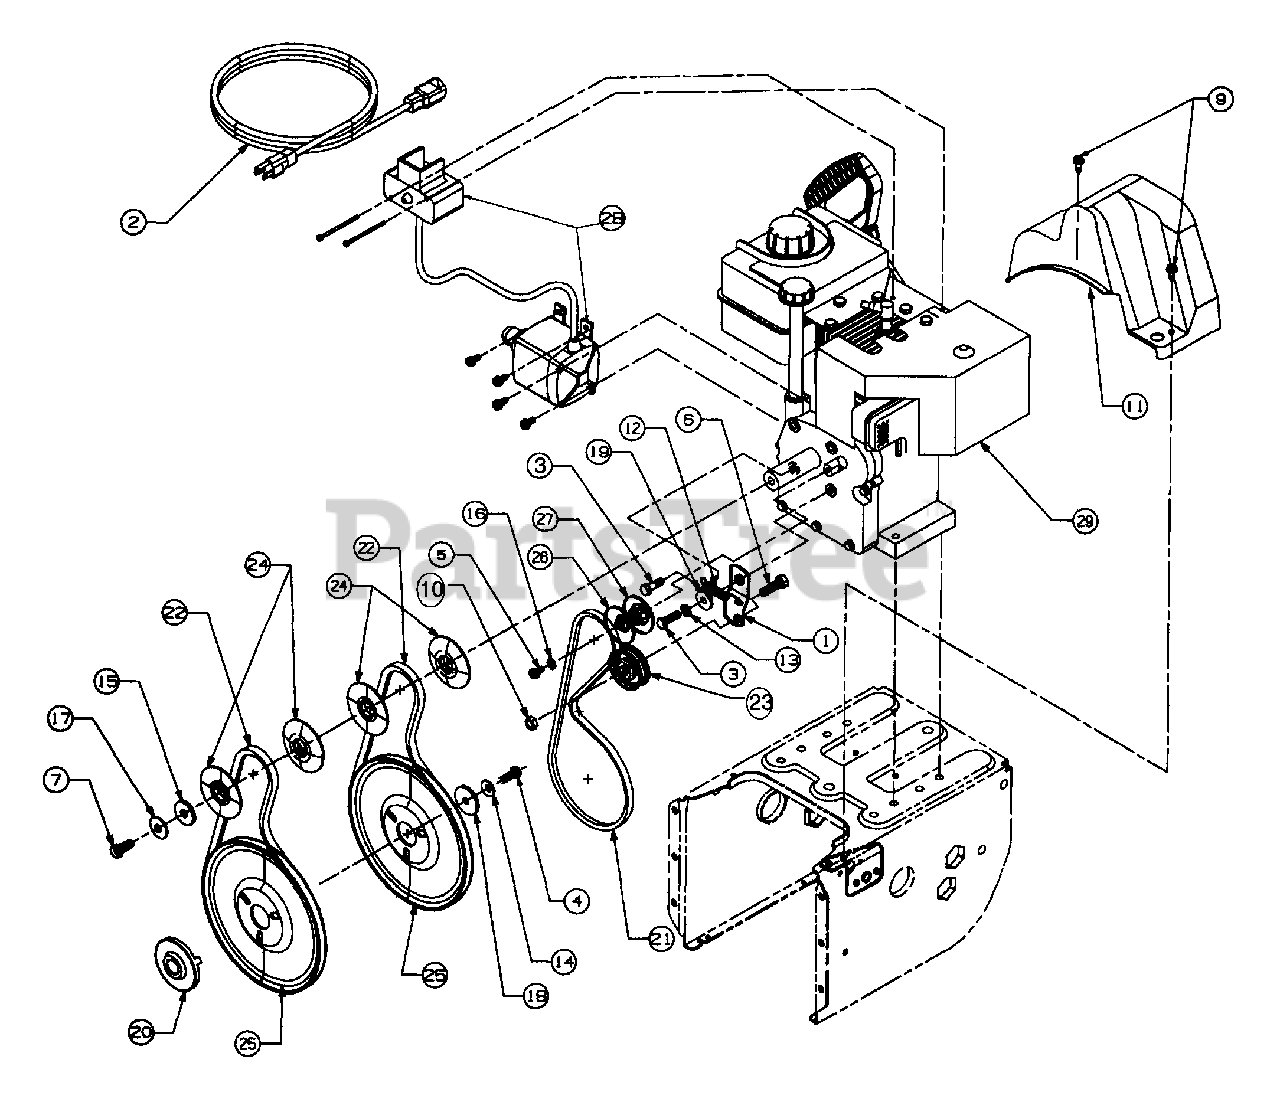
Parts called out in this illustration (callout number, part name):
3	Screw
4	Screw
5	Screw
6	Screw
7	Screw
9	Screw
10	Jam Nut
11	Belt Cover
12	Spring
13	Flat Washer
14	Bell Washer
15	Flat Washer
16	Lock Washer
17	Bell Washer
18	Flat Washer
19	Shoulder Spacer
20	Adapter Pulley
21	V-Belt
22	V-Belt Matched
23	Flat Idler
24	Half Pulley
25	Auger Pulley
26	Pulley Half
27	Pulley Half
28	Starter
